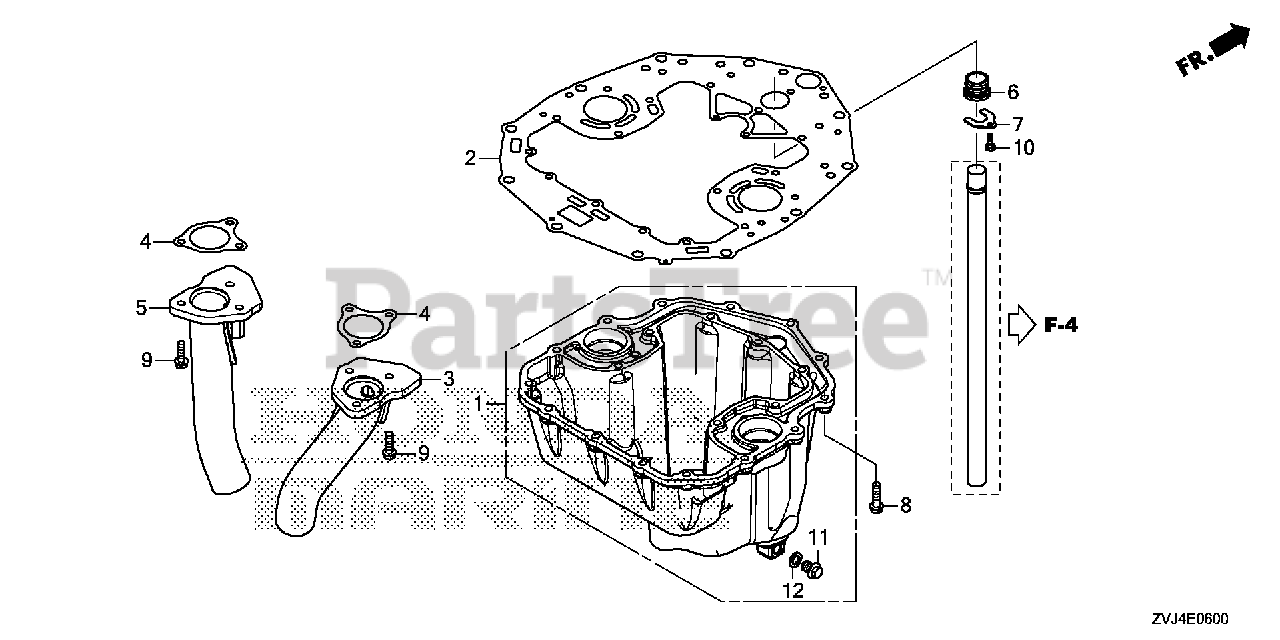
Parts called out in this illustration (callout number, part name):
1	PAN ASSY., OIL *TGRAY* (GRAY)
2	GASKET, OIL PAN
3	PIPE, R. EX.
4	GASKET, EX. PIPE
5	PIPE, L. EX.
6	GROMMET, WATER TUBE
7	PLATE, WATER TUBE
8	BOLT-WASHER (8X35) (SUS)
9	BOLT-WASHER (8X28) (SUS)
10	BOLT, HEX. (6X16)
11	BOLT, DRAIN PLUG
12	WASHER, DRAIN PLUG (12MM)
